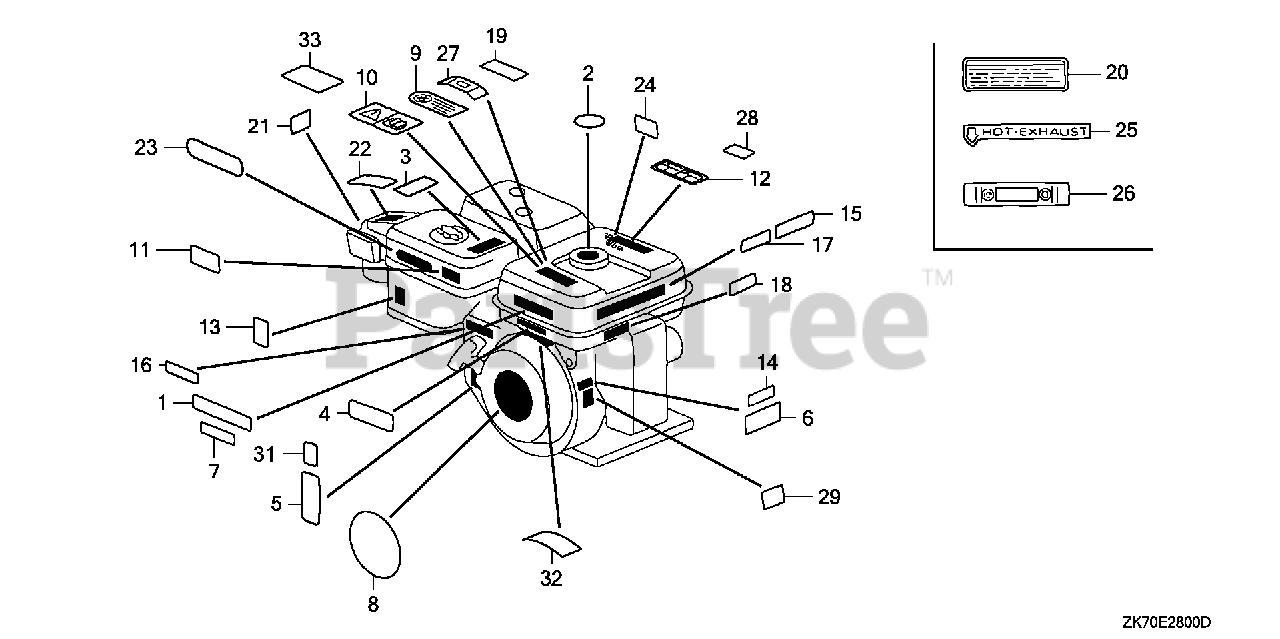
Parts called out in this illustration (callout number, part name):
1	LABEL, CAUTION (ENGLISH, ETC.)
4	LABEL (E-SPEC)
8	EMBLEM (GX120)
13	MARK, CHOKE
17	MARK, OIL ALERT (ENGLISH)
31	LABEL, WARNING (NOT CERTIFIED FOR SALE)
